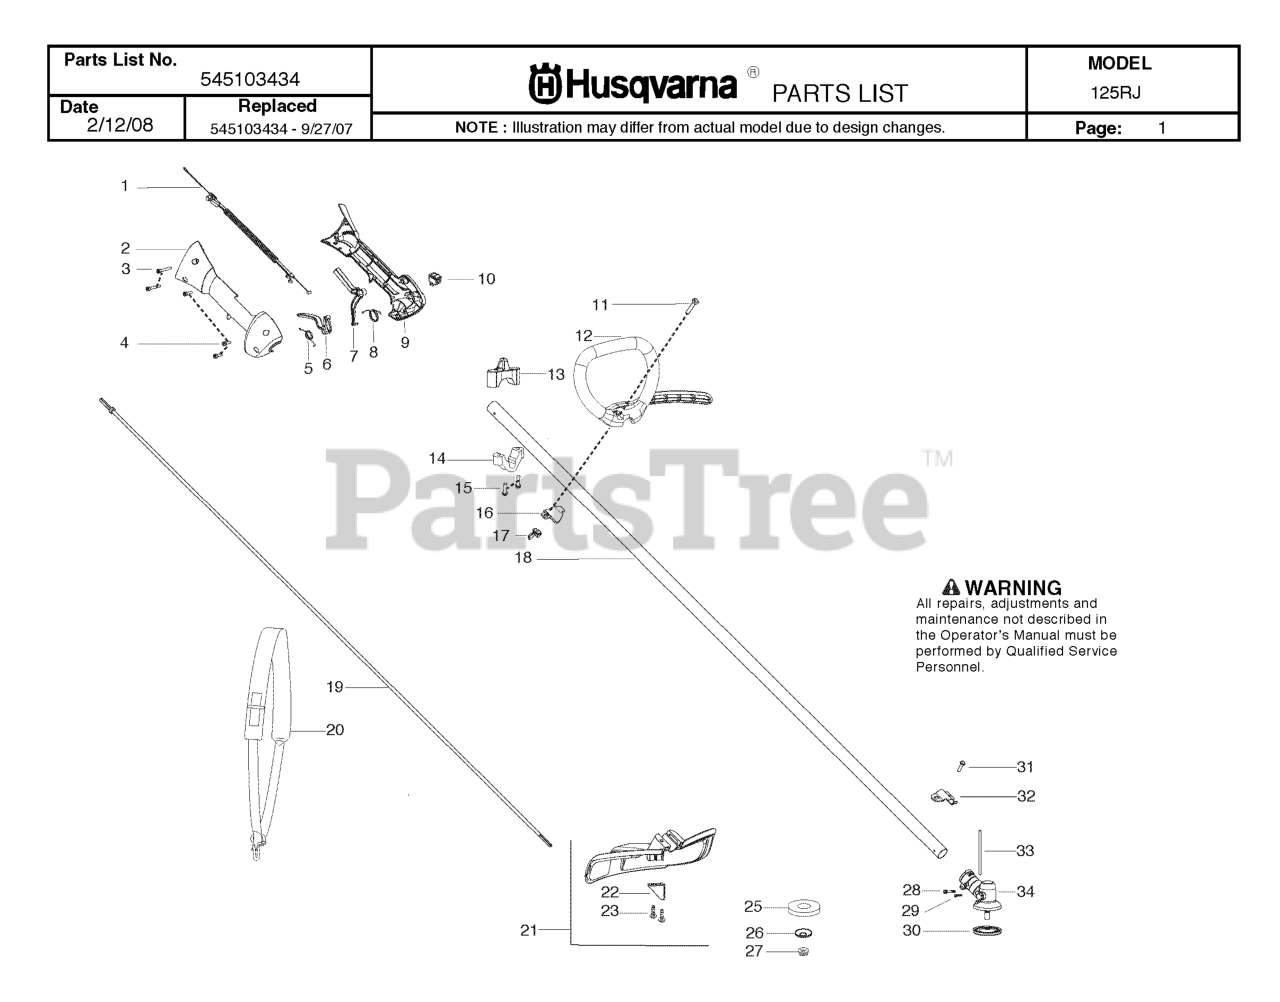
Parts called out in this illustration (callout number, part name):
1	ASSY-CABLE WIRE HARNESS
2	HOUSING-THROTTLE RH
4	SCREW M4 X 1.75 PT 16MM
5	SPRING TRIGGER
6	TRIGGER THROTTLE
7	THROTTLE LOCKOUT
8	SPRING LOCKOUT
9	HSG THROTTLE LH
10	KIT SWITCH
11	BOLT, TYPE 2
12	ASSY HANDLE JBAR
13	CLAMP HARNESS UPPER
14	CLAMP HARNESS LOWER
16	CLAMP ASSIST HANDLE
17	WINGNUT, TYPE 2
18	KIT-DRIVESHAFT
20	Harness-w/o warning
21	KIT COBI SHIELD
22	Limiter - Line
25	SUPPORTING CUP
26	SUPPORT FLANGE
27	GEARHEAD NUT - BRUSHCUTTER
28	SCREW - CARB. ADAPTOR
30	DRIVE DISC
31	SCREW 1/4-20 X 7/8 (TAP
32	BRACKET SHIELD STRAIGHT SHAFT
33	LOCKING PIN
34	ASSY GEARBOX
